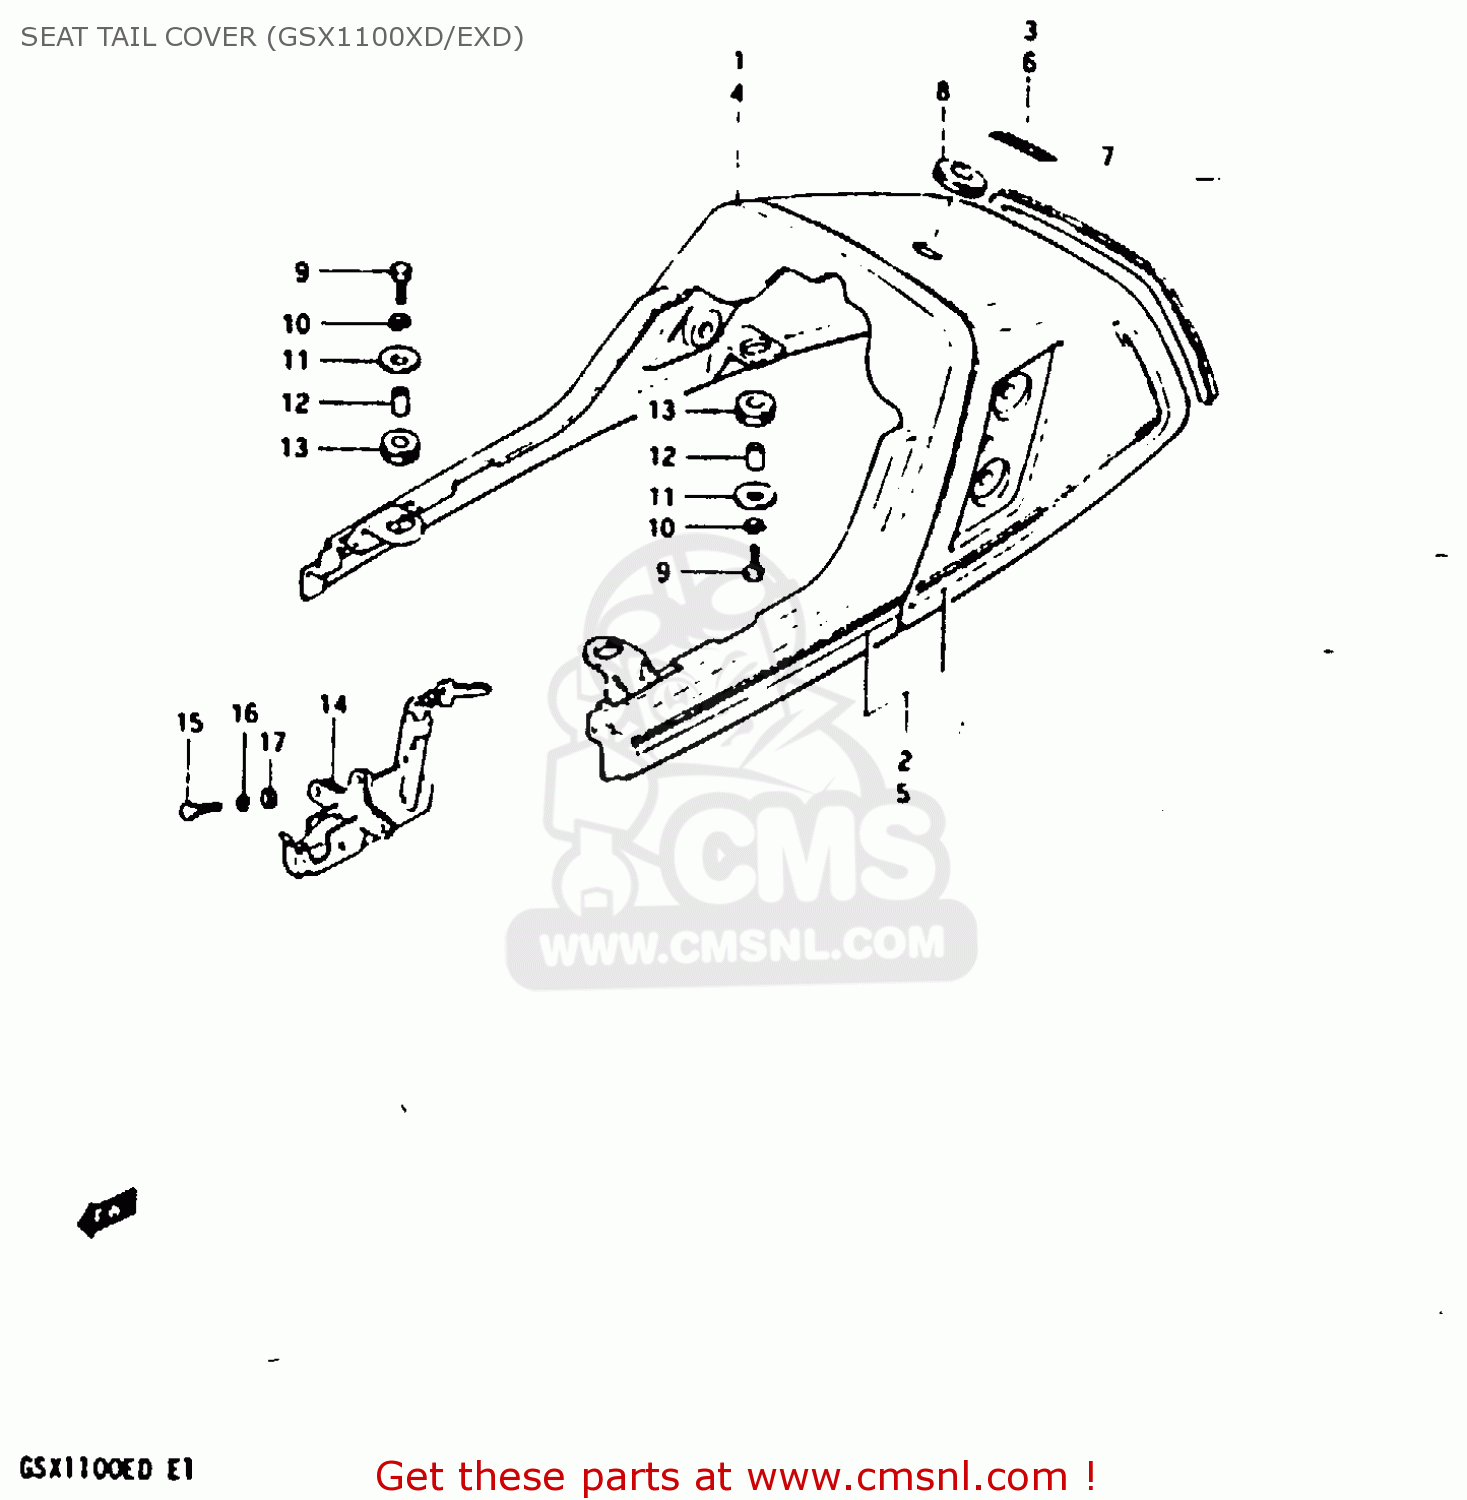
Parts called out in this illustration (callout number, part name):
1	TAIL COVER, SEAT (BLACK)
2	TAPE SET, SEAT TAIL COVER
3	EMBLEM (BLUE)
4	TAIL COVER, SEAT (RED)
5	TAPE SET, SEAT TAIL COVER
6	EMBLEM
7	RUBBER,BLIND,SEAT TAIL COVER
8	GROMMET,SEAT LOCK HOLE
9	BOLT
10	LOCK WASHER
11	WASHER(6,5X22X1.6)
12	SPACER(6.5X10.5X12)
13	CUSHION
14	LOCK SET,SEAT
15	BOLT
16	LOCK WASHER
17	WASHER
